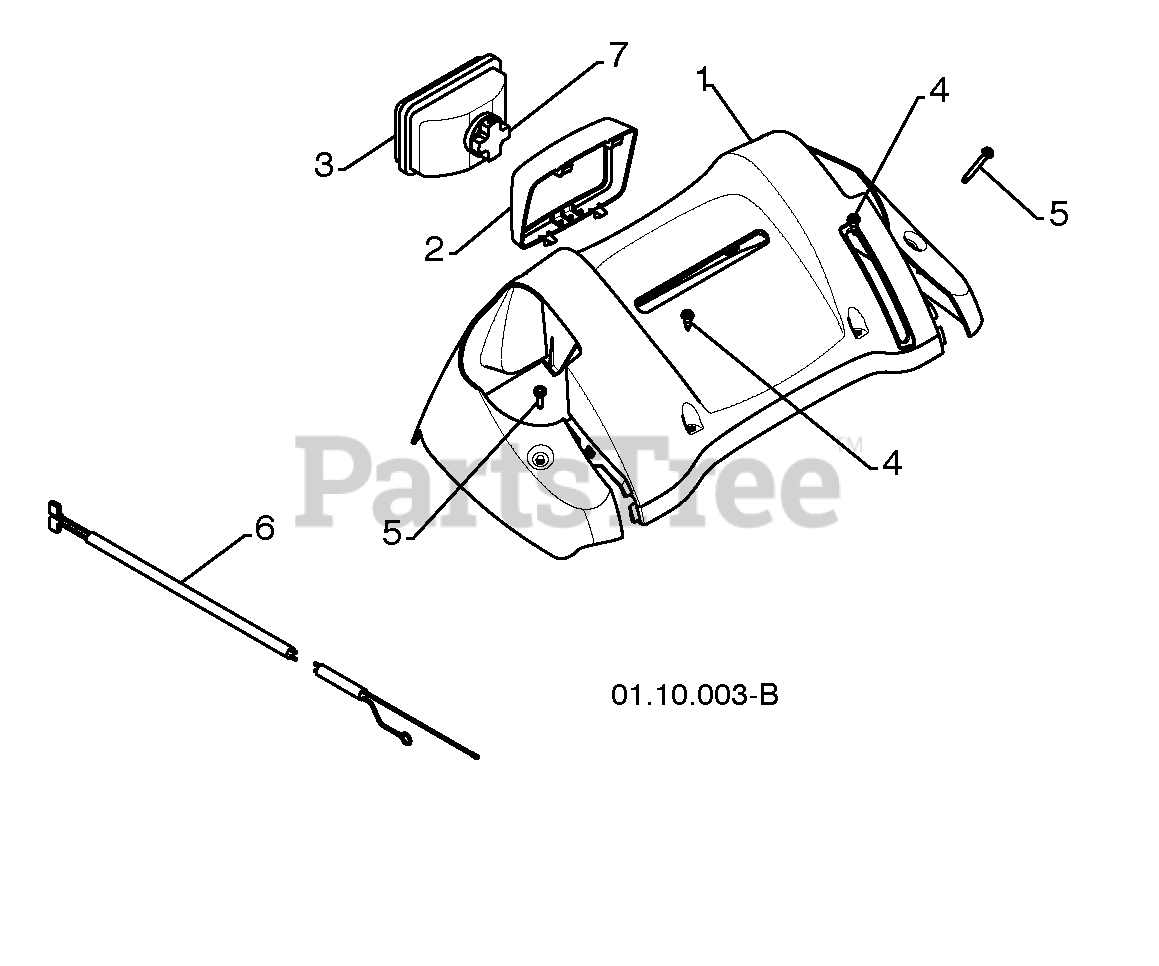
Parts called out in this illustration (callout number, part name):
1	CONSOLE PANEL
2	HEADLIGHT BEZEL
3	FLOOD HEADLIGHT
4	SCREW 10-24 X .625
5	SCREW 10-24 X 1.25
6	WIRE HARNESS
7	BULB
